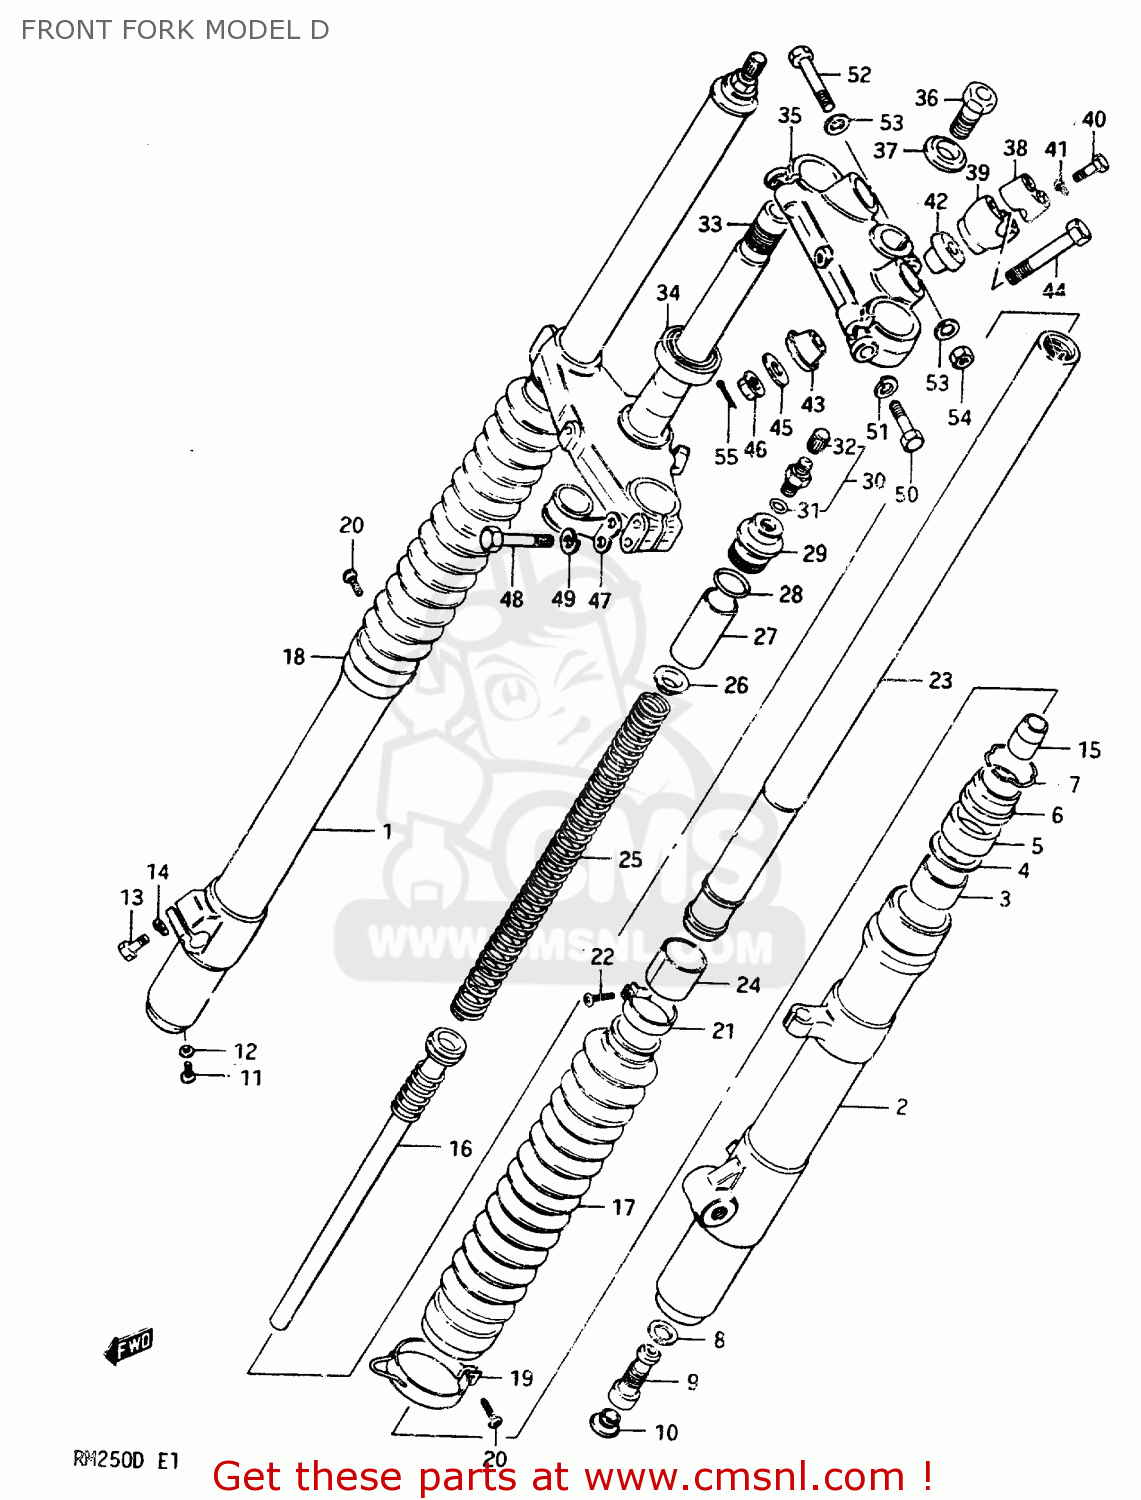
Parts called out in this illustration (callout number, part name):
1	DAMPER SET
2	TUBE,OUTER,LEFT
3	METAL,SLIDE
4	WASHER
5	SEAL,OIL
6	SEAL,DUST
7	RING,STOPPER
8	GASKET,FORK CYLINDER
9	VALVE,DF
10	CAP,FRONT FORK DF
11	SCREW 4X6
12	GASKET,DRAIN,PLUG (NAS)
13	BOLT
14	WASHER,LOCK
15	PIECE,FRONT FORK OIL LOCK
16	CYLINDER,FRONT FORK
17	BOOT,FRONT FORK COVER
18	BAND,BOOT,UPPER
19	BAND,FRONT FORK BOOT
20	SCREW
21	BAND,FRONT FORK BOOT
22	SCREW
23	TUBE,INNER
24	PISTON
25	SPRING,FRONT FORK
26	GUIDE,SPRING
27	SPACER,FRONT FORK SPRING
28	O RING
29	CAP,FORK INNER TUBE
30	VALVE,FRONT FORK AIR
31	O-RING
32	CAP,VALVE AIR
33	STEM,STEERING
34	BEARING(30X55X17)
35	HEAD,STEERING STEM
36	BOLT
37	WASHER
38	HOLDER,HANDLE UPR
39	HOLDER,HANDLE LWR
40	BOLT
41	WASHER,LOCK
42	DAMPER,UPR
43	DAMPER,LWR
44	BOLT,HANDLE HOLDER
45	WASHER,HANDLEBAR HOLDER
46	NUT
47	GUIDE,CABLE
48	BOLT 8X40
49	WASHER,LOCK
50	BOLT
51	WASHER,LOCK
52	BOLT 8X50
53	WASHER
54	NUT
55	PIN 20X20
